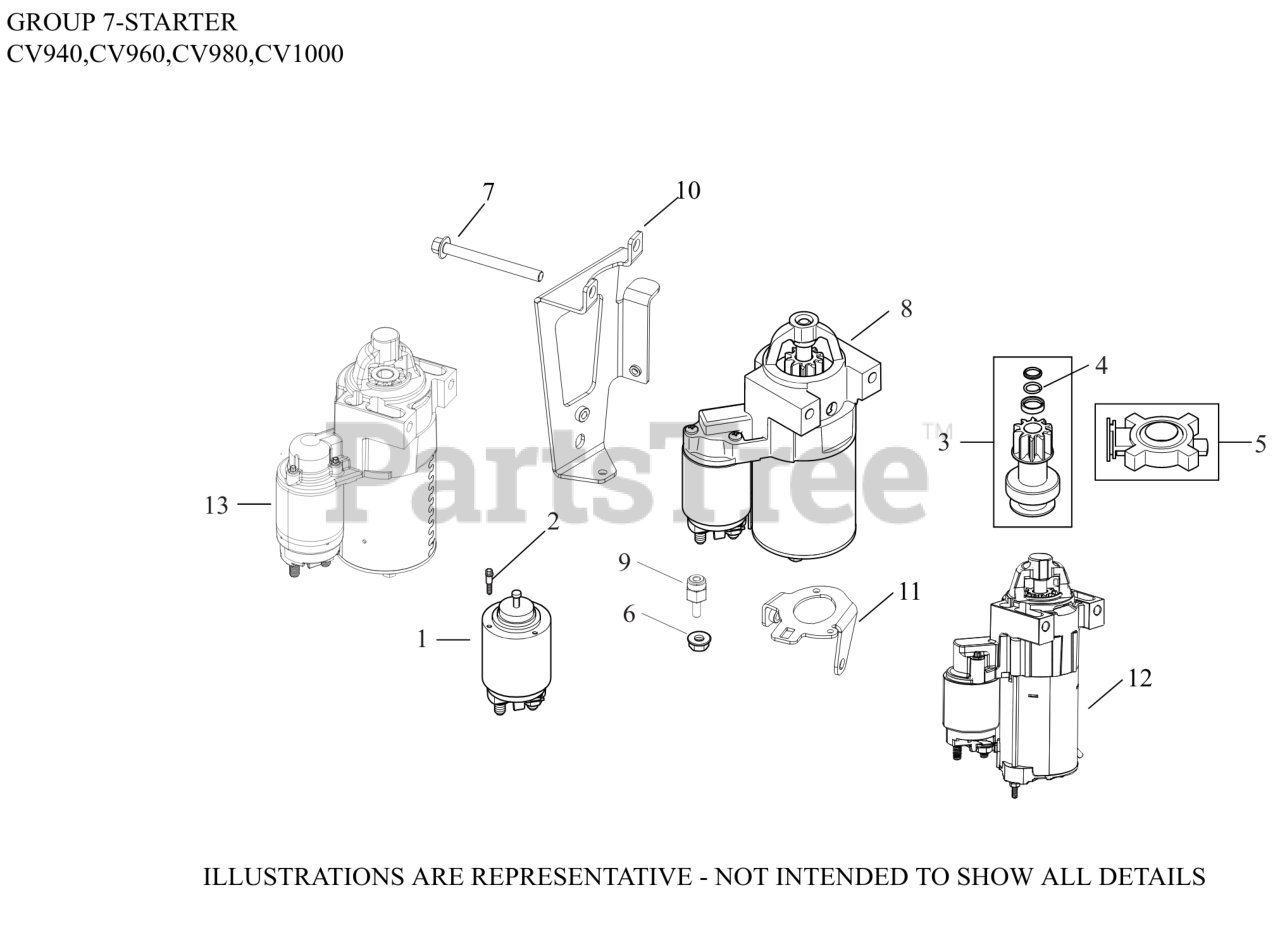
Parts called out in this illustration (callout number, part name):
6	NUT, FLG M8X1.25
7	SCREW, FLG M8X1.25X80
8	STARTER, SOLENOID SHIFT-(#2509824S)
